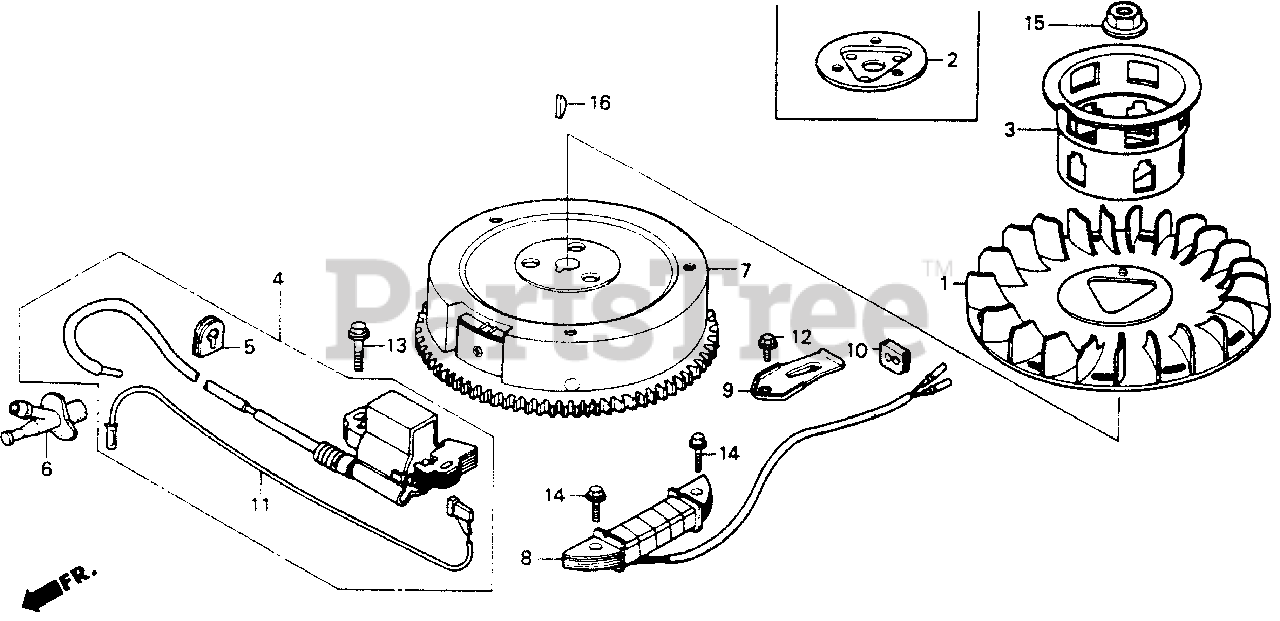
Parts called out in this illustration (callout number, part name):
1	FAN, COOLING
2	PLATE, COOLING FAN SETTING
3	PULLEY, STARTER
4	COIL ASSY., IGNITION (NA USE ALT:30500-ZE9-003)
5	GROMMET, IGNITION
6	CAP ASSY., NOISE SUPPRESSOR
7	FLYWHEEL
8	COIL ASSY., CHARGE
9	CLAMP, WIRE
10	GROMMET, WIRE
11	WIRE, STOP SWITCH
12	BOLT, FLANGE (6X12) (CT200)
13	BOLT, FLANGE (6X28)
14	BOLT, FLANGE (6X28)
14	BOLT, FLANGE (6X25) (CT200)
15	NUT, SPECIAL (16MM)
16	KEY, SPECIAL WOODRUFF (25X18)
